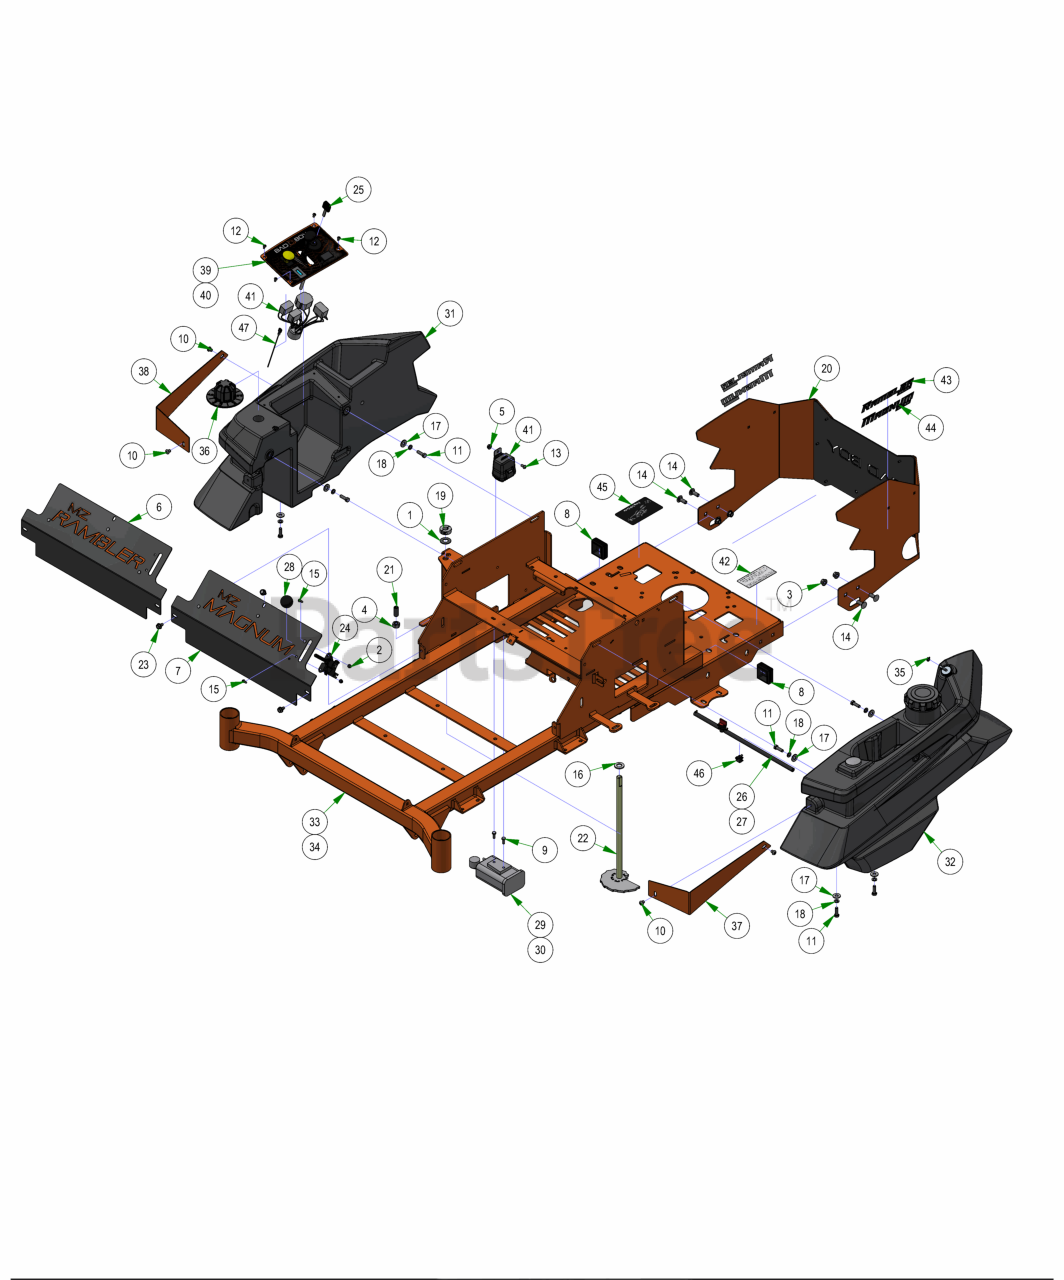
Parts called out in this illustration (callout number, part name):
1	.625 ID x 1.250 OD x .062 THK F/W Nylon
2	10-24 NYLON INSERT LOCKNUT ZINC
3	3/8-16 NYLON INSERT FLANGE LOCKNUT (GR.F) ZINC
4	1/2-13 HEX NUT ZINC
5	1/4-20 HEX SERRATED FLANGE NUT HARD/ZINC
6	2023 MZ Rambler Cooler Cover Assembly
7	2023 MZ Magnum Cooler Cover Assembly
8	2X2 Frame Plug
9	M6-1.0 X 16MM DIN 933 HEX TAP BOLT (CL 8.8) ZINC
10	5/16-18 x 3/8 Button SOC CAP BLACK
11	5/16-18 X 1 HEX CAP SCREW (GR.5) ZINC
12	10-32 X 3/8 BUTTON SOCKET CAP SCREW 18-8 STAINLESS STEEL
13	1/4-20 X 1/2 BUTTON SOCKET CAP SCREW 18-8 STAINLESS STEEL
14	3/8-16 X 1 CARRIAGE BOLT (GR.5) ZINC
15	10-24 X 5/8 BUTTON SOCKET CAP SCREW 18-8 STAINLESS STEEL
16	.635 ID X 1.120 OD X .140 THICK FLAT WASHER NYLON
17	5/16 USS FLAT WASHER (7/8 OD) ZINC
18	5/16 SPLIT LOCKWASHER ZINC
19	5/8" Split Collar
20	MZ Rear Cover Assembly
21	Dial Rod Plunger
22	ZT Deck Height Bar Assembly
23	5/16-18 X 1/2 HWH unslot (F) tcs zinc
24	MZ Brake Plate Assembly w/ Brake Cable
25	Ignition Key
26	15" Fuel Line Assembly
27	31" Fuel Line Assembly
28	Throttle Knob
29	MZ Kohler 42" EPA Canister Assembly
30	MZ Kohler EPA Canister Assembly
31	2025 Aven, Magnum & Rambler RH Consol Tank
32	2025 Aven, Magnum & Rambler LH Fuel Tank
33	2025 MZ 42-48 Frame
34	2025 MZ-Avenger 54-60 Frame
35	MZ Tank Hose Clamp 1/4 Vinyl
36	MZ/ZT Deck Height Dial
37	2025 Metal tank insert - Right
38	2025 Metal Tank insert - left
39	2025 Small Mower Control Panel Assembly
40	2023 Rambler Control Panel Assembly
41	2025 Wiring Harness with Clips and Lights
42	2025 EPA Build Date Punch Decal
43	Rambler Back Plate Decal
44	Magnum Back Plate Decal
45	Pump Belt Route Decal-Pump Plate
46	Edge Clip With Ziptie
47	2017 MZ/ZT/MAV Tach Wire Assy
